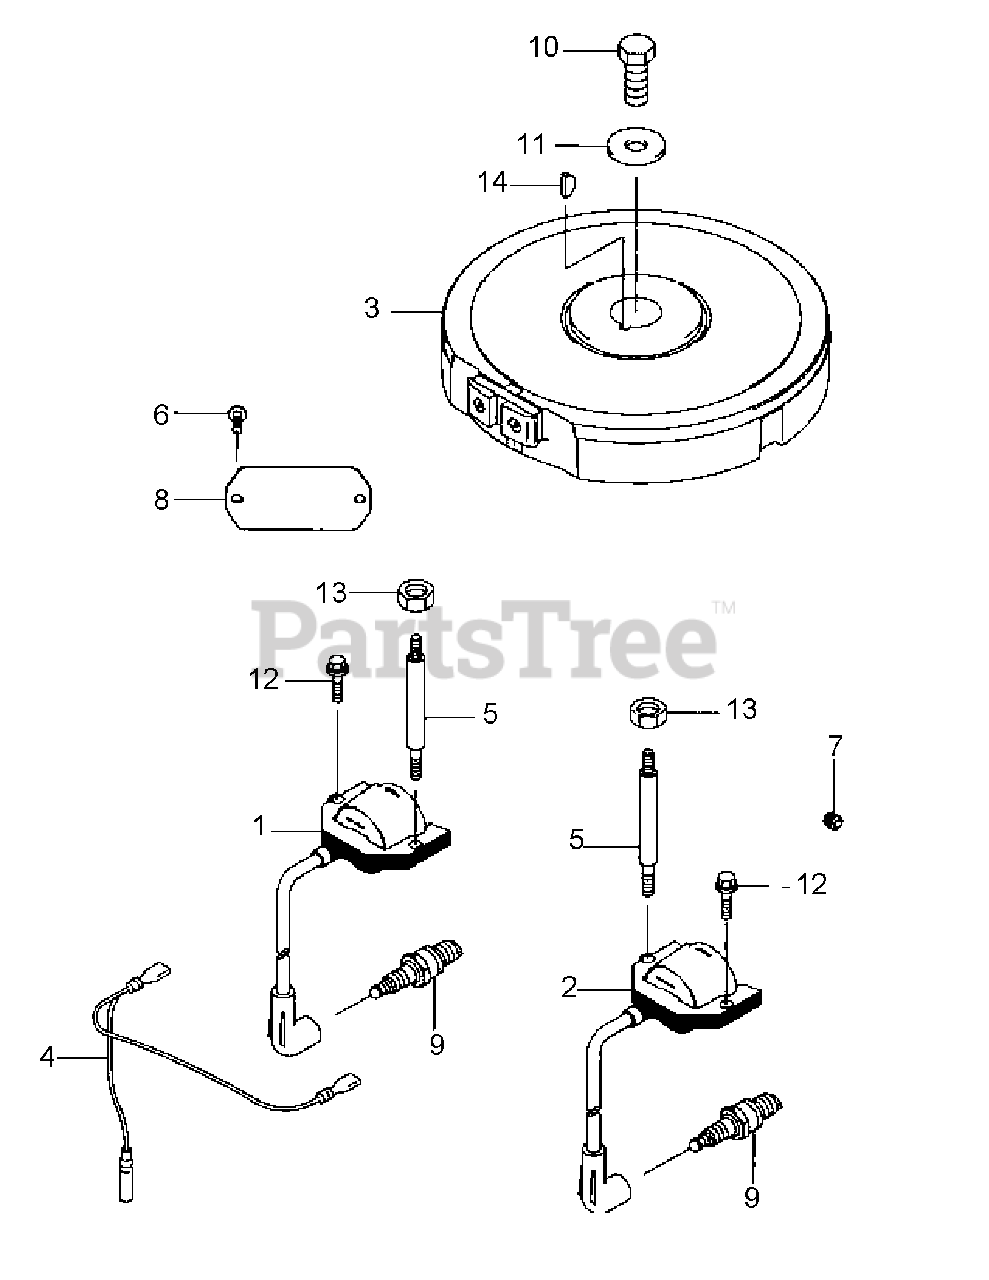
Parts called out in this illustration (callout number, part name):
1	IGNITION COIL ASSY.
2	IGNITION COIL ASSY.
9	SPARK PLUG
12	FLANGED BOLT
14	WOODRUFF KEY
